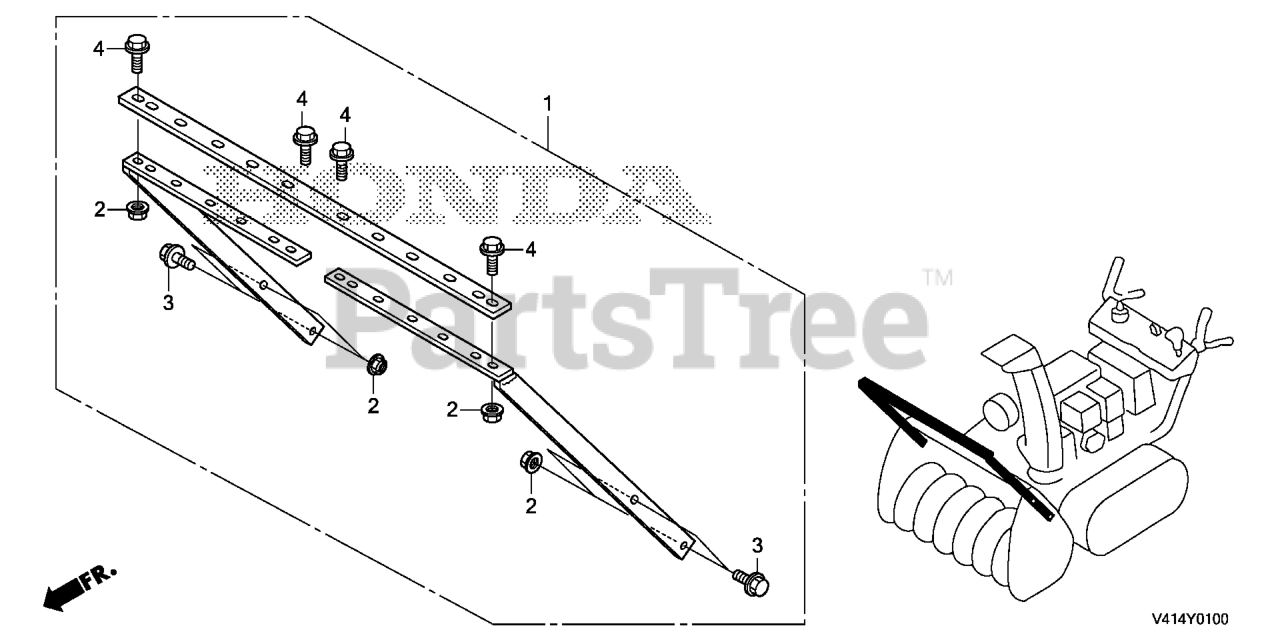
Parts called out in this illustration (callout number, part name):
1	BREAKER KIT, DRIFT (NA USE ALT:06768-V45-305AH)
2	NUT, SELF-LOCK (8MM)
3	BOLT, FLANGE (8X20)
4	BOLT, FLANGE (8X25)
